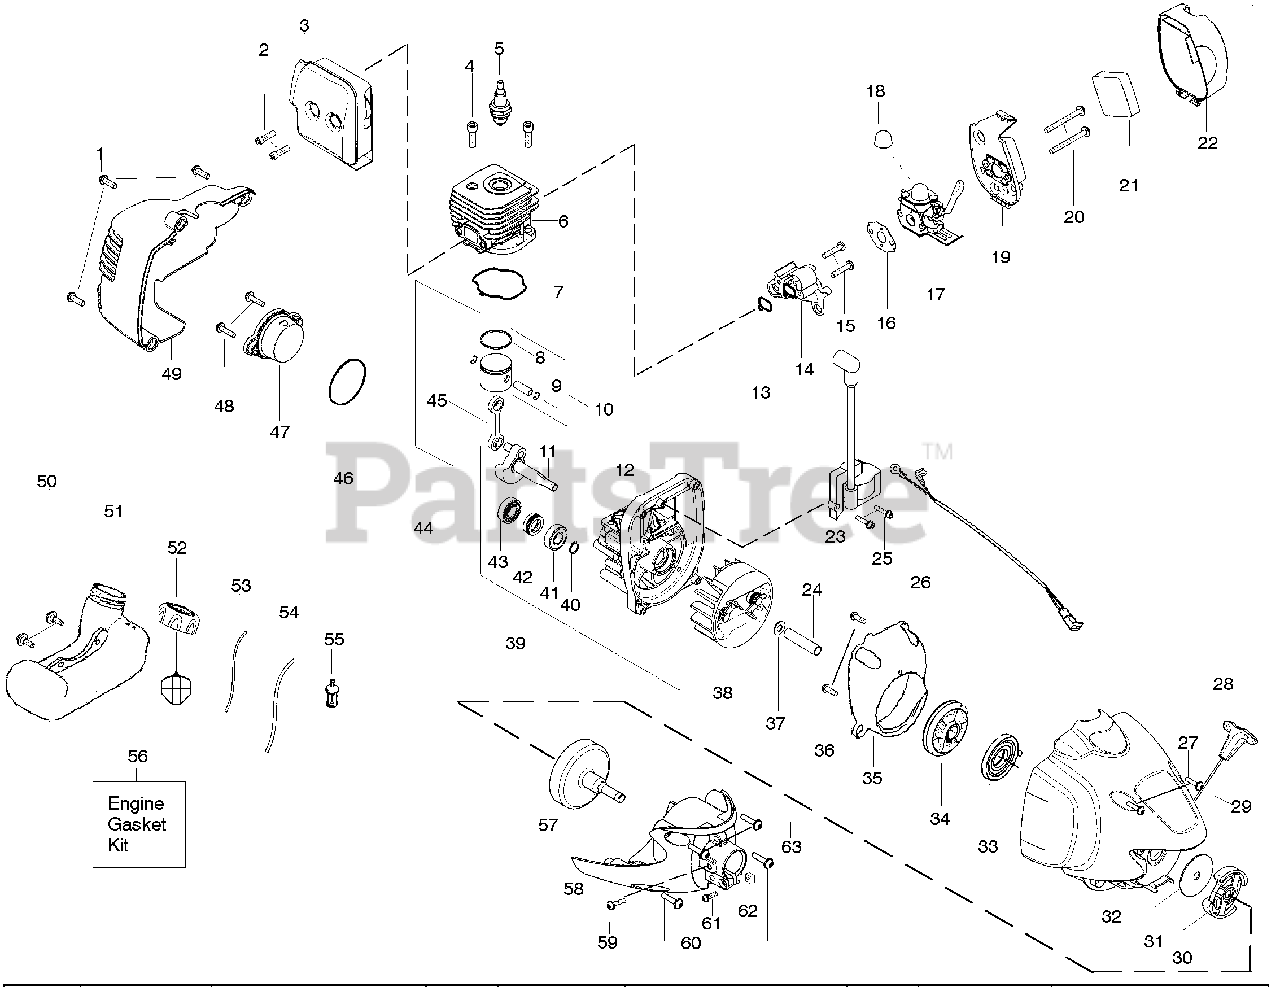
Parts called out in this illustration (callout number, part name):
3	Assy-Muffler/Shield
4	Screw-Cylinder
5	Spark Plug (RCJ 6Y)
7	Seal-Cylinder (kit)
8	Piston Ring
9	Retainer-Piston Pin
10	Kit - Piston
11	Assy-Crankshaft
12	Assy-Crankcase
13	Seal-Cyl/Carb.(kit)
14	Adapter-Carb.
16	Gasket-Carb. (kit)
17	Kit-Carb.(C1U-W19)
21	Foam-Air Filter
22	Cover-Air Box
23	Ignition Module
24	Spacer-Flywheel
26	Assy-Switch wire
28	Handle-Starter
31	Washer-Clutch
32	Assy.-Fan Hsg
33	Spring-Starter
34	Kit-Starter Pulley
37	Washer-Clutch Flat
38	Assy-Flywheel
39	Assy-C'case & C'shaft
40	Retain. Ring-C'shaft
41	Outer Bearing
43	Inner Bearing
44	Kit-piston/rod
45	Kit-Conn. Rod
46	O-Ring-C'case (kit)
47	Assy-Plug
50	Retainer-Tank
51	Assy-Fuel Tank (incl.
52	filter, lines & fuel cap)
53	Assy-Fuel Cap
54	Kit-Fuel Line (Small)
55	Kit-Fuel Line (Large)
56	Assy-Fuel Pickup
57	Kit-Engine Gasket
58	Assy-Clutch Drum
59	Assy-Clutch Cover
